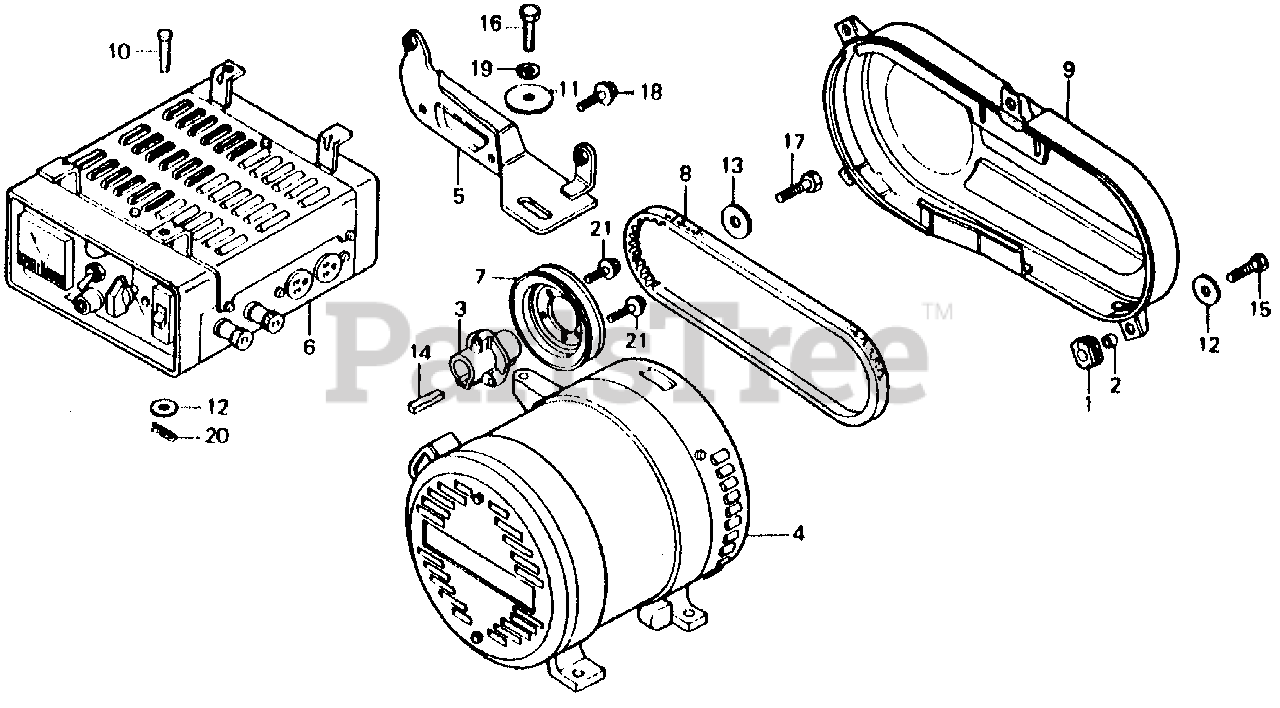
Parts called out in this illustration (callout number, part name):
1	RUBBER, TANK CUSHION (NOT AVAILABLE)
2	COLLAR, DISTANCE
3	BOSS, DRIVE PULLEY (NOT AVAILABLE)
4	GENERATOR ASSY. *R8/NH31/NH1* (BRIGHT RED/MC KINLEY WHITE/ BLACK)
5	STAY, ALTERNATOR
6	BOX ASSY., CONTROL *R8* (BRIGHT RED)
7	PULLEY (FOR 60) (NOT AVAILABLE)
8	V-BELT (B-37)
9	COVER, BELT *R8* (BRIGHT RED)
10	PIN, CONTROL BOX SETTING
11	WASHER (8MM)
12	WASHER, FLAT (20MM)
13	WASHER, LOCK (8MM)
14	KEY (7X7X33)
15	BOLT, HEX. (6X20)
16	BOLT, HEX. (8X22)
17	BOLT, HEX. (8X25)
18	BOLT-WASHER (8X20)
19	WASHER, SPRING (8MM)
20	PIN, LOCK (8MM)
21	BOLT, FLANGE (6X16)
